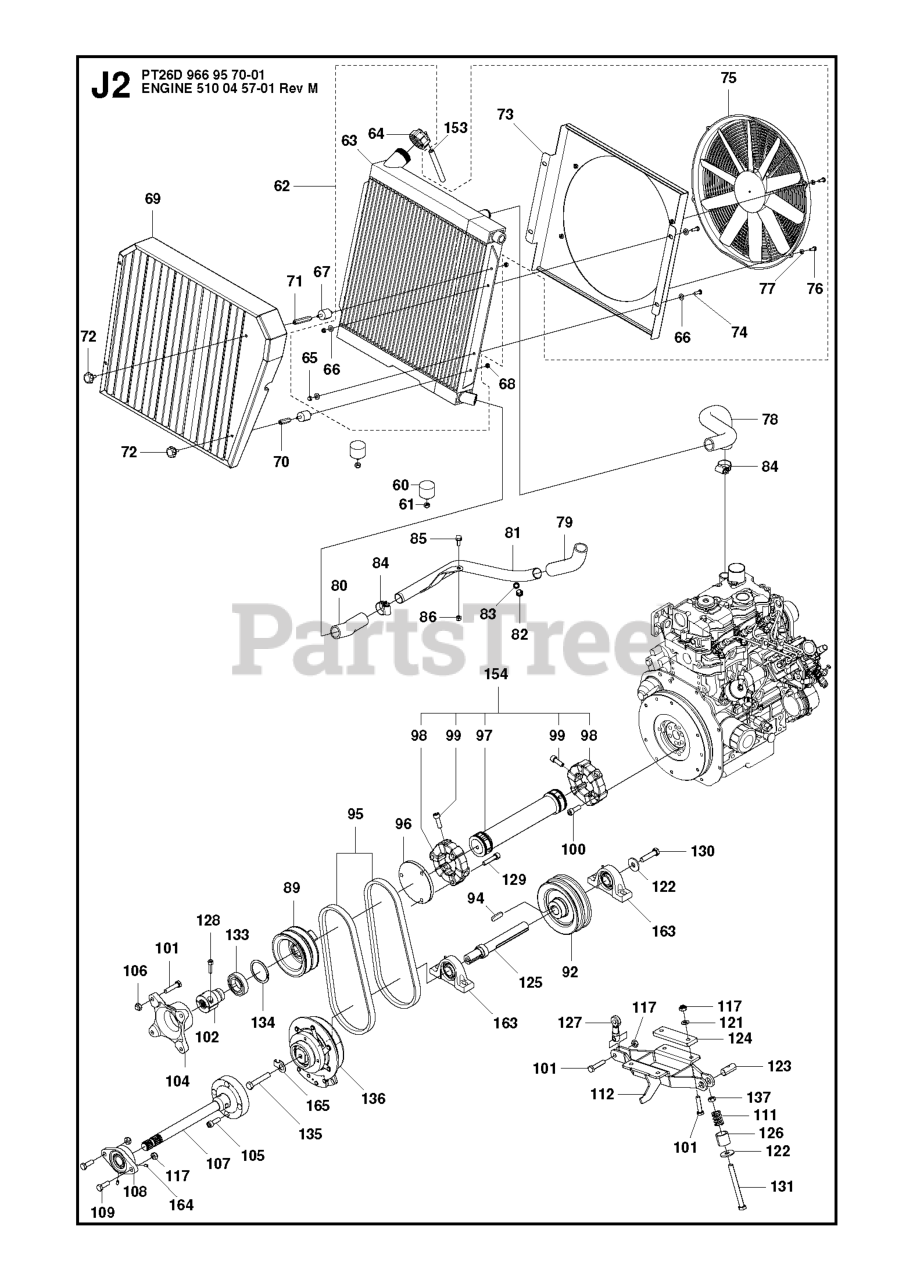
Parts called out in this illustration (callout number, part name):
60	ANTIVIBRATION ELEMENT
61	LOCKNUT M8
62	RADIATOR ASSY
65	LOCKNUT M6
66	WASHER - 15X7.3X1.6
67	ANTIVIBRATION ELEMENT RADIATOR
68	LOCKNUT M6
75	ELECTRIC FAN
76	Screw
77	WASHER - M6
78	HOSE COOLING WATER
79	HOSE COOLING WATER
80	HOSE COOLING WATER
81	TUBE COOLING WATER
82	SCREW EHHM
86	LOCKNUT M8
100	SCREW IHSCM M10X30 12.9 ZPB L
101	REPL BY 725 25 00-71
105	SCREW IHSCM M10X30 12.9 ZPB L
106	NUT
108	BEARING UNIT FYTB 25TF
117	NUT
121	WASHER
129	SCREW IHSCM M10X45 12.9 ZPB L
137	NUT
